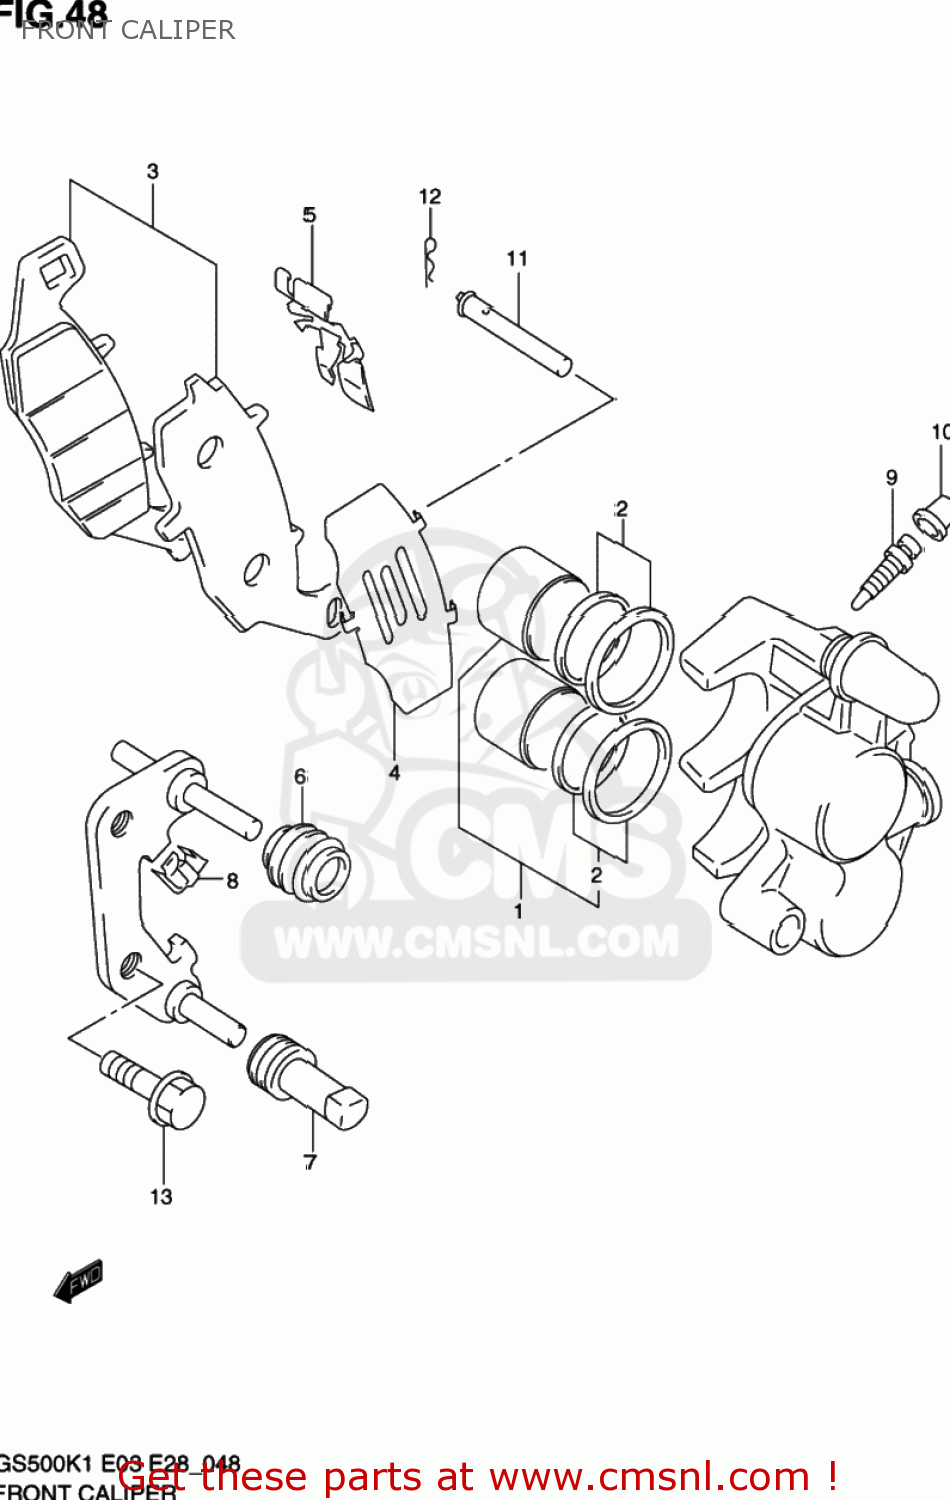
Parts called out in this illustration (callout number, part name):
1	PISTON SET
2	SEAL SET,PISTO
3	PAD SET,R (NAS)
4	SHIM,PAD
5	SPRING,PAD,R
6	BOOT,AXLE
7	INSULATOR,AXLE
8	GUIDE,PAD
9	BLEEDER
10	CAP,BLEEDER PLUG
11	PIN,PAD
12	CLIP,PAD PIN
13	BOLT
